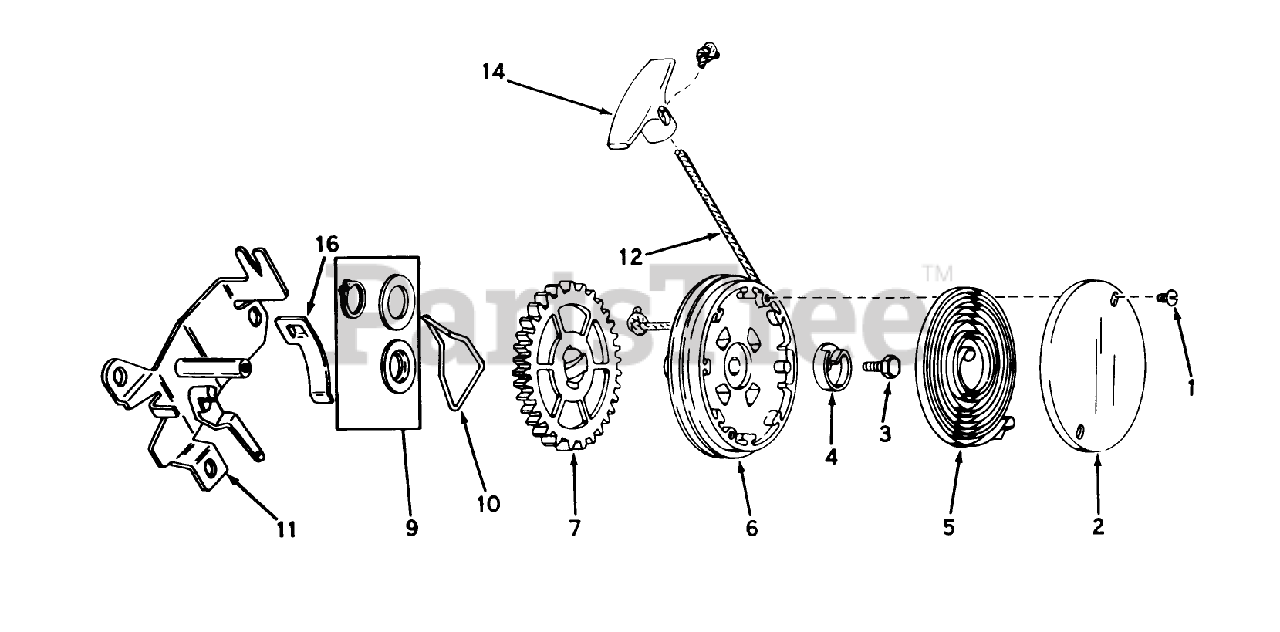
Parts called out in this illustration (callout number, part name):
1	Screw
2	Cover, Spring
3	Screw, Hex Washer Head
4	Hub Spring
5	Spring, Rewind
6	Pulley Assy. (Incl. No. 9)
9	Kit, Thrust Wash. Snap Rg.
10	Brake
11	Bracket Assy., Mounting
12	Rope-Starter
14	Handle-Starter
16	Clip Rope
